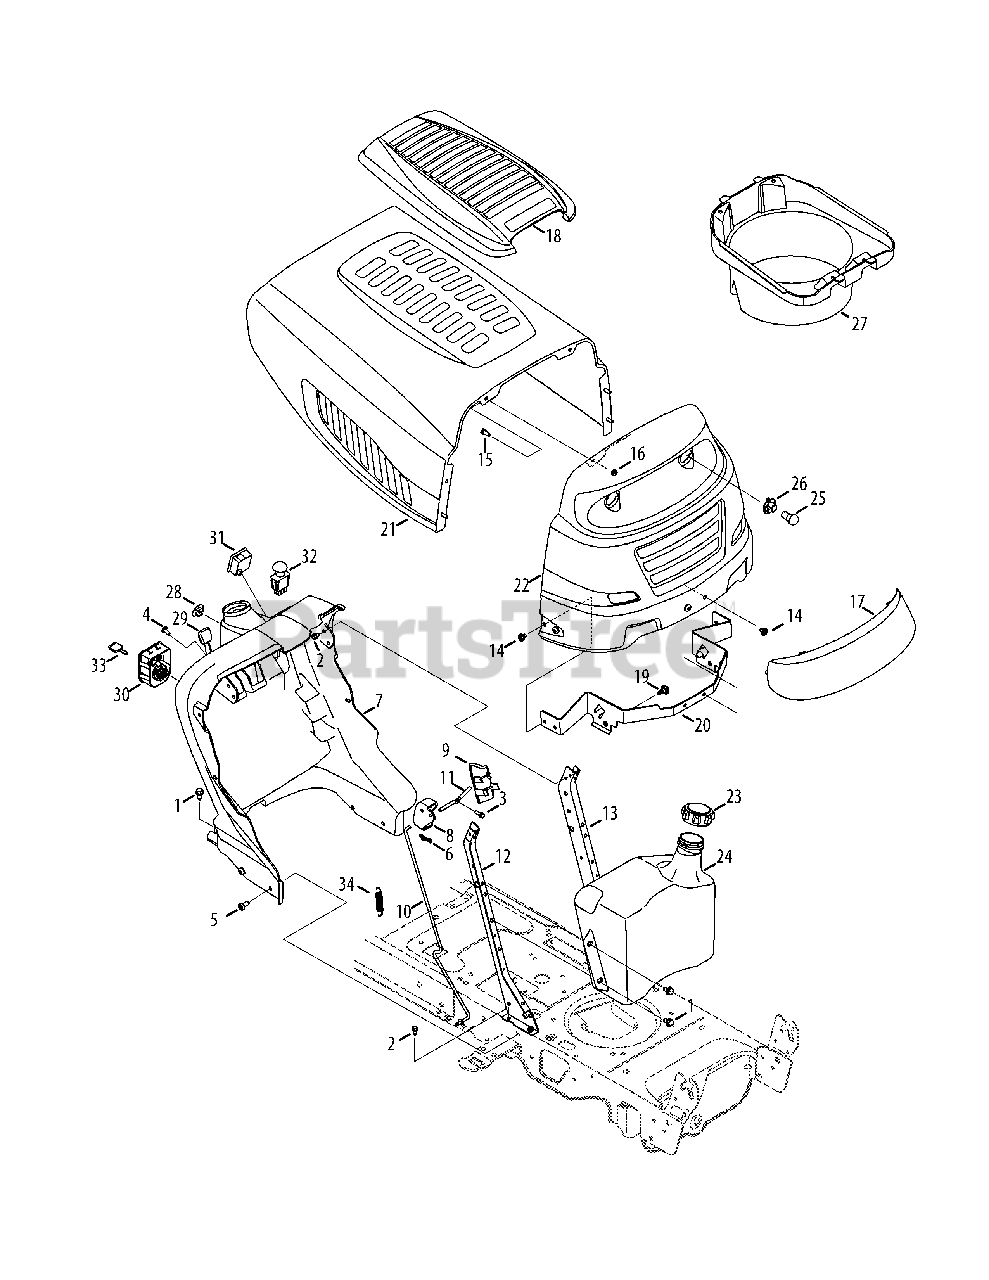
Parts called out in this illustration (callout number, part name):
1	Taptite Screw ,5/16-18X.750
2	Taptite Screw ,1/4-20X0.500
3	Hi-Lo Screw, 1/4-15X0.750
4	Screw, 1/4-14X0.625
5	Taptite Screw ,5/16-18X0.750
6	Bow Tie Cotter Pin
7	Dash Panel
8	Dash Lever
9	Cruise Cover
10	Control Rod
11	Lever
12	RH Support Plate
13	LH Support Plate
14	Taptite Screw ,5/16-18X0.375
15	Hex Screw, 1/4-20x.620
16	Flangelock Nut, 1/4-20
17	Grill Lens
18	Hood Scoop
19	Shoulder Screw, .43X.29 5/16-18
20	Hood Pivot Bracket
22	Grill
23	Fuel Cap
24	Fuel Tank
26	Lamp Socket
28	Choke Plug
29	Throttle/Choke Cable
30	Key Switch Module
31	Hour Meter
32	Electric PTO Switch
34	Extension Spring, .500 DIA x 2.733 LG
